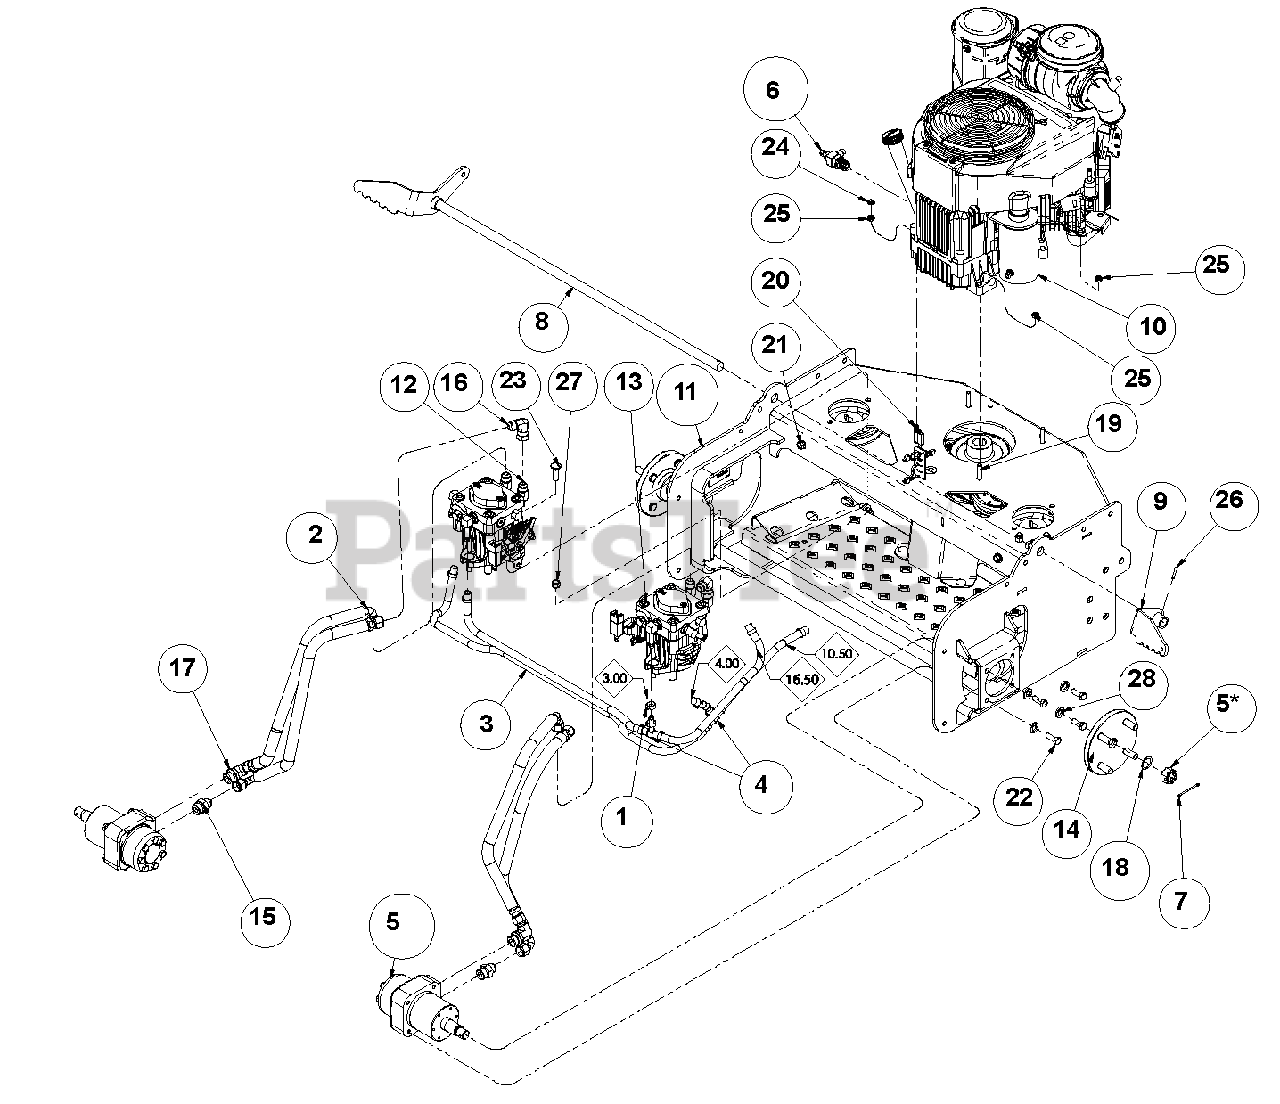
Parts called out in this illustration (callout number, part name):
1	Clamp, Hose - 1/2" Pinch
2	Hose Assembly
3	Hose, 3/8 SAE 30R7 Fuel & Oil
4	Fitting, TUN 3/8 Hose
5	Motor, Wheel HGM-12P-7172 (*Includes Castle Nut, tighten to 163 N•m (120 lbf-ft))
6	Fitting, Oil Drain
7	Pin, Cot .125 x 2.00 Extp Y
8	Weldment, Brake Shaft
9	Weldment, RH Brake Arm
10	Engine, Kawasaki 19HP FH580V
11	Weldment, Deck Frame w/Decals
12	Assembly, HYD Pump (See Pump Components on page 16.)
13	Assembly, HYD Pump (See Pump Components on page 16.)
14	Assembly, Rear Wheel Hub
15	Fitting, ADP 3/4-16FJIC x 7/8-14MOR
16	Fitting, ADP MJIC-FSWJIC 6500-08-08
17	Fitting, ADP JIC-ORB 2062-10-8S
18	Bushing, Mach., .75 x 1.25 x .048
19	Bolt, .3125-18 x 1.50 Hex 5 Y
20	Bolt, .3125-18 x 1.75 Hex 5 Y
21	Bolt, .375-16 x 1.00 FGH 8 Y
22	Bolt, .375-16 x 1.00 Hex 5 Y
23	Bolt, .375-16 x 1.25 CRG 5 Y
24	Nut, .3125-18 JAM GR5 Y
25	Locknut, .3125-18 Nyloc Y
26	Pin, Roll .156 x 1.00
27	Locknut, .375-16 Nyloc Y
28	Washers, .375 Medium Spring Lock
